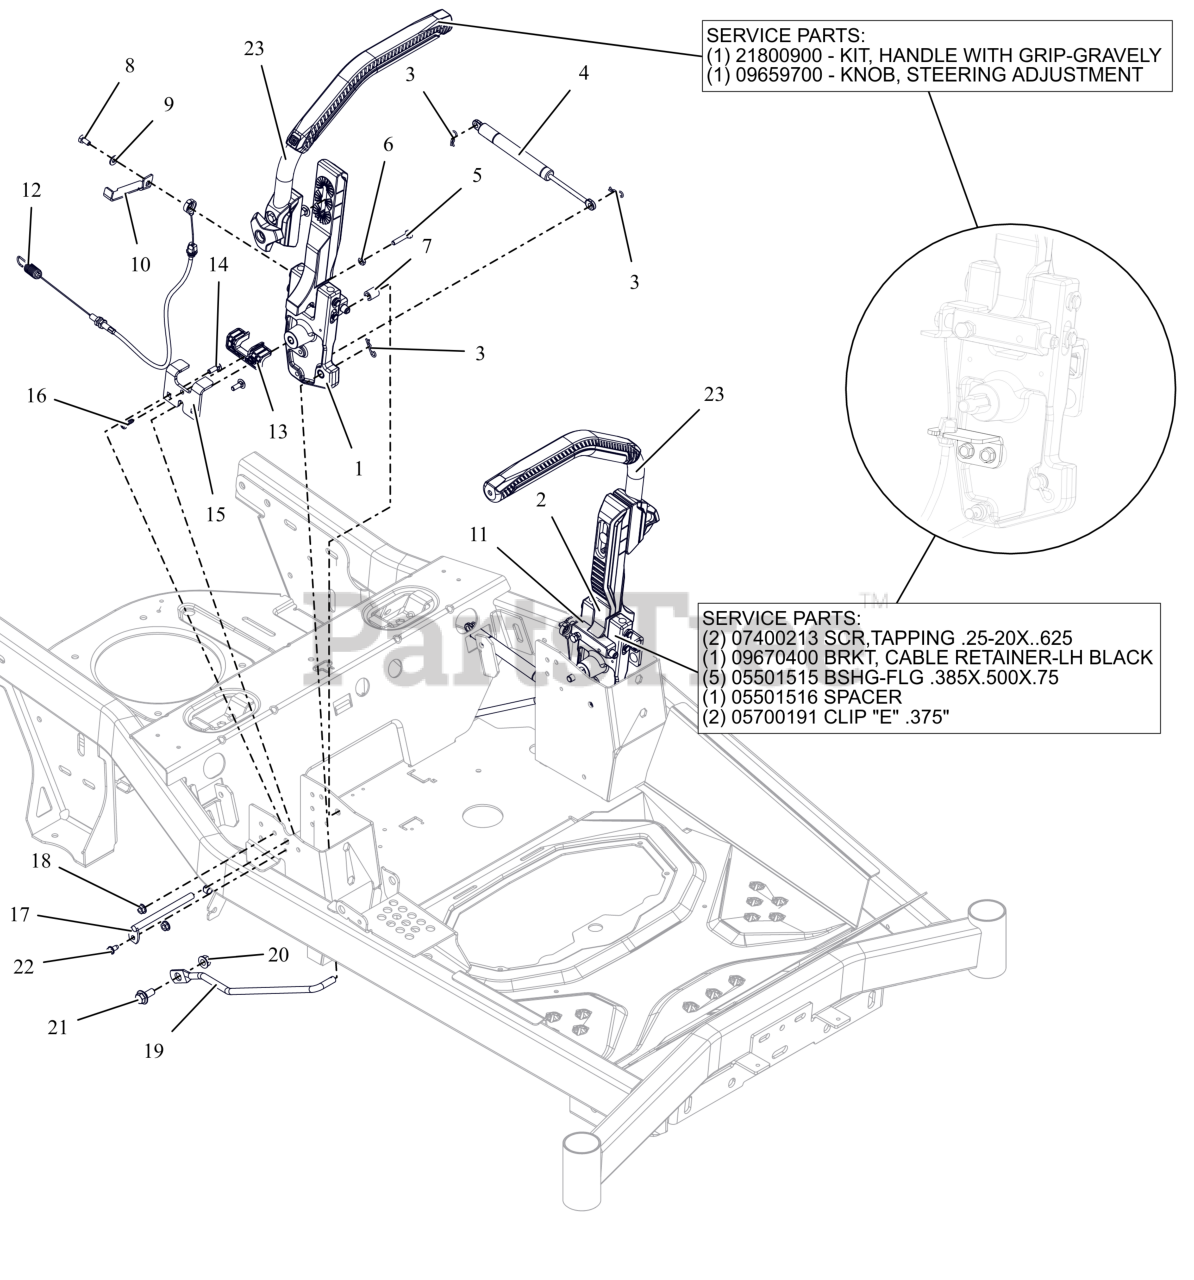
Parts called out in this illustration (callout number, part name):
1	ASM- CONTROLS LWR -RH GRAVELY
1	SELF TAPPING SCREW, .25-20X.625
1	BRKT- CABLE RETAINER
1	BSHG-FLG .385X.500X.75
1	SPACER SLEEVED .385X.500X1.045
1	3/8" E RETAINING RING EXTERNAL
2	ASM- CONTROLS LWR -LH GRAVELY
2	SELF TAPPING SCREW, .25-20X.625
2	BRKT5- CABLE RETAINER LH-BLK
2	BSHG-FLG .385X.500X.75
2	SPACER SLEEVED .385X.500X1.045
2	3/8" E RETAINING RING EXTERNAL
3	PIN, HAIR #213 .08X1.19 ZCC
4	DAMPER- STRAIGHT MOUNT
5	BLT, HEX 0.25-20X1.25F GR5 ZCC
6	NUT-JAM .250-20 G2 ZCC
7	SPCR- SNAP-ON 1/2 X 1 1/2
8	BLT, HEX 0.375-16X1 GR5 EP80 ZC120
9	WSHR,FLT .281X.625X.065 ZCC
10	BRKT, PARKING BRK ENG R (BLACK)
11	BRKT, PARKING BRK ENG L (BLACK)
12	CABLE- PARK BRAKE
13	STEERING, PLASTIC LINER
14	BLT, RHSN .25-20X.750 G5 ZCC
15	PLATE- BRAKE STOP
16	SCR-TAP 12-14X.75PLSTITE @BLZC
17	PIN- FIXED STEERING PIVOT
18	NUT-LK-CTR-FLG .25-20 ZC120
19	WIREFORM- STEERING LINKAGE
20	NUT-LK-CTR-FLG .375-16 GF ZCC
21	BLT- SHLDR .375-16X.100X.72
22	SCR-TAP .25-20X.50 HWH ZCC
23	ASM-HANDLE BAR -GRAVELY
23	KIT, TUBE WITH GRIP-GRAVELY
23	KNOB- STEERING ADJUSTMENT
